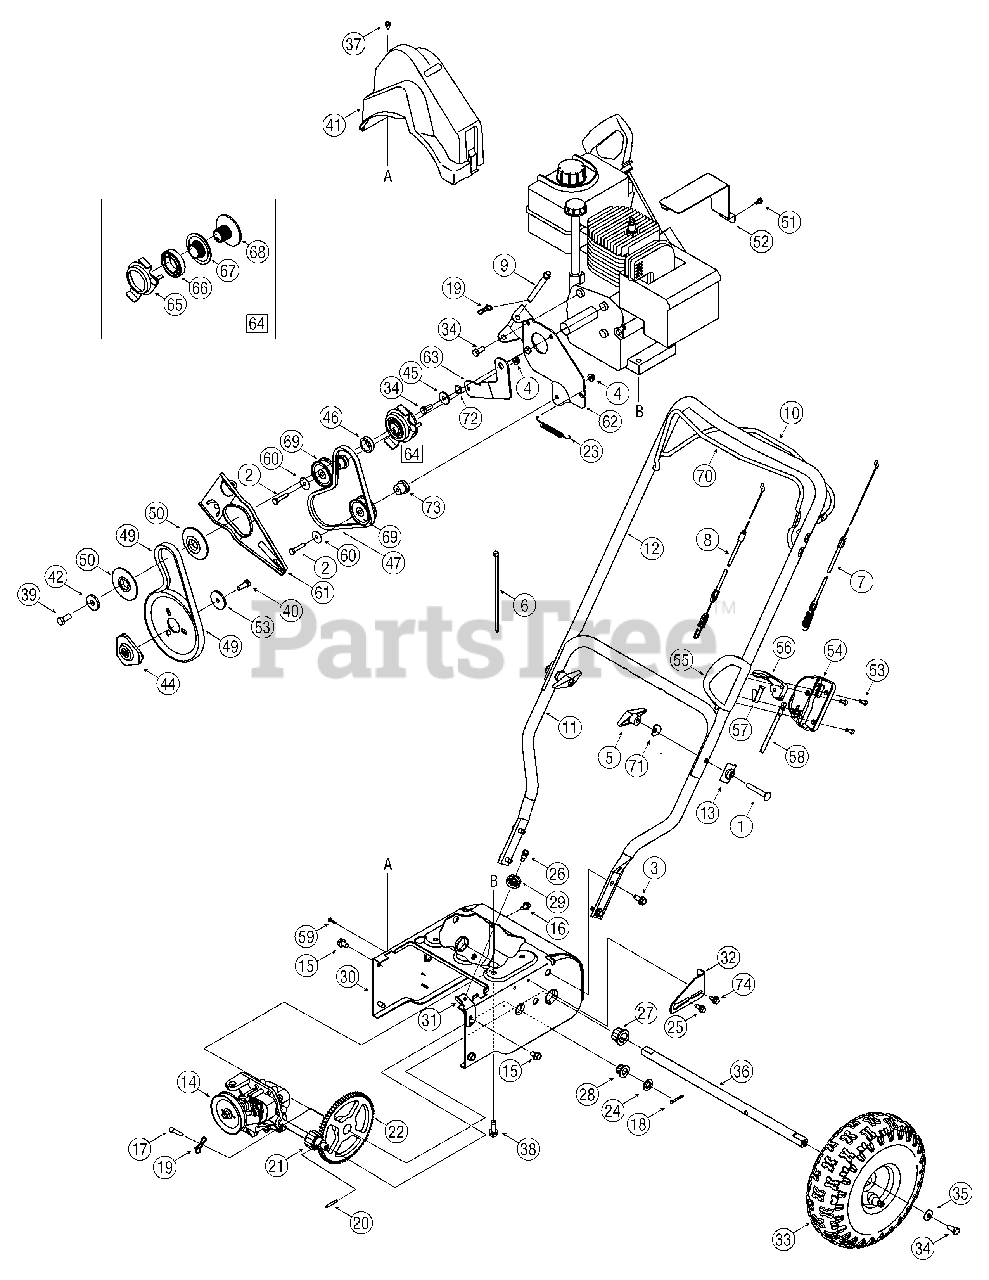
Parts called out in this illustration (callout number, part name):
1	Carriage Screw 5/16-18 x 2.25"
2	Hex Screw 1/4-20 x 1.25"
3	Screw, 5/16-18 x .75"
4	Flange Lock Nut 1/4-20
5	Lock Nut Knob 5/16-18
6	Cable Tie
7	Drive Cable
8	Auger Cable
9	Pivot Rod
10	Drive Control
12	Upper Handle
13	Handle Tab
14	Transmission Assembly
15	AB Screw 5/16-18 x .625
16	Screw, 1/4-20 x 1.25"
17	Clevis Pin
18	Cotter Pin, 1/8 x 1.0
19	Bow Tie Cotter Pin 72
20	Roll Pin
21	Pinion 14T
22	Gear 70T
23	Extension Spring
24	Flat Washer
25	Shoulder Screw 1/4-20
26	Carriage Screw 1/4-28
27	Hex Flange Bearing
28	Hex Flange Bearing
29	Cable Roller
31	Auger Cable Bracket
33	Wheel Assembly Snow Hog Gray
34	Lock Bolt 5/16-24 x 0.75"
35	Bell Washer
37	Hex Screw, #10-16 x.500
38	TT Sems Screw 3/8-16 x 1.0"
39	Hex Bolt 3/8-24 x 0.875"
40	Lock Bolt 5/16-24 x 0.875"
41	Belt Cover
42	Flat Washer,.406ID x 1.25OD
43	Flat Washer,.34ID x 1.50OD
44	Pulley: Adapter,.75 Dia.
45	Shoulder Spacer
46	Shoulder Spacer
47	V-Belt, 3L x 25.00 LG
49	V-Belt, 3/8 x 26.680 Lg.
49	Auger Pulley
50	Pulley Half
51	Screw, #10-16 x.500
52	Heat Shield
53	Screw #10-16
54	Speed Selector Housing - Lwr
55	Speed Selector Housing - Upr
56	Speed Selector Housing -Lever
57	6 Speed Shift Lever Spring
58	Speed Control Cable
59	Screw .159 x .610
60	Flat Washer .265 x 1.0 x .030
63	Drive Wheel Idler Bracket
64	Multi-Speed Pulley Assembly
65	6 Speed Assembly Cup
66	Ball Bearing
67	Pulley Half
68	Drive Pulley Half
69	Idler Pulley Assembly
71	Saddle Washer
72	Wave Washer .531 x .781 x .013
73	Shoulder Spacer .60 x .790 x.538
74	Screw, 1/4-20 x 1.25"
